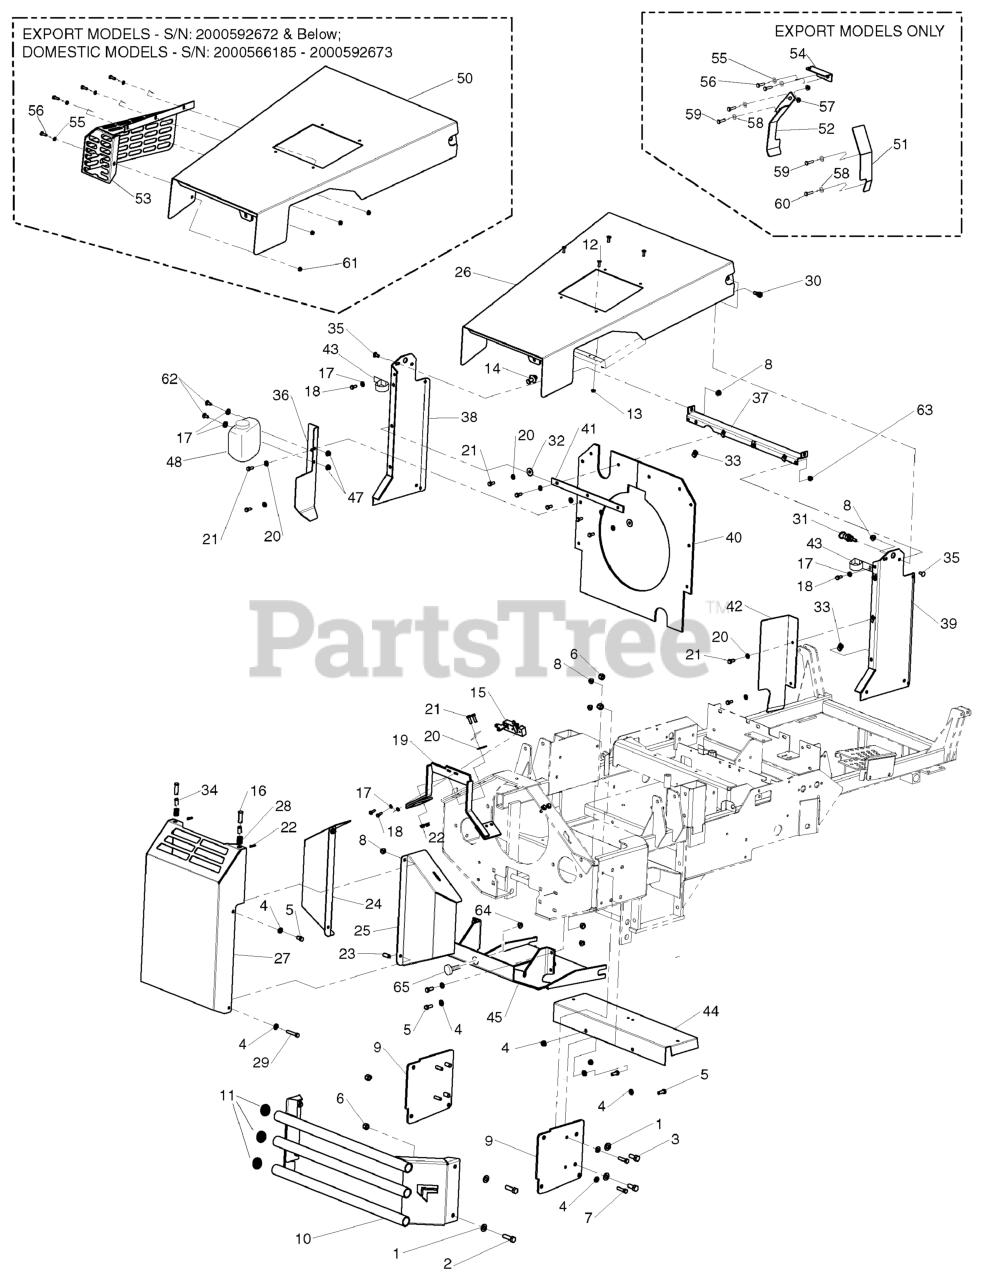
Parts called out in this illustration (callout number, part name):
1	WASHER, 1/2 SAE
2	BOLT, 1/2-20 X 1-3/4" GD8 CZ
3	BOLT, 1/2-20 X 1-1/4" GD5 CZ
4	WASHER, 3/8 SAE
5	BOLT, 3/8-16 X 1" GD5 CZ
6	NUT, Hex, Nylon Lock, 1/2-20
7	BOLT, 3/8-16 X 1-1/4" GD5 CZ
8	NUT, 3/8-16 HEX NYLOCK FLANGE
9	PLATE, BUMPER MOUNT - RED
10	WELD, BUMPER, SERVICE IS4500 - RED
11	PLUG, PANEL, 1.25 - BLACK
12	SCREW, 1/4-20 X 1/2" ALLEN BH
13	NUT, 1/4-20 NYLOCK FLANGE
14	BOLT/WASHER ASM HOOD LATCH
15	HOOD LATCH, IS5000
16	BUMPER, RUBBER, 5/16-18
17	WASHER, 1/4 SAE
18	BOLT, 1/4-20 X 1" GD5 CZ
19	WELD, MOUNT HOOD LATCH - RED
20	WASHER, 5/16" SAE
21	BOLT, 5/16-18 X 1" GD5 YZ
22	NUT, 5/16-18 HEX NYLOCK FLANGE
23	SPACER, .38 X .50 X 1.00
24	WELD, BUMPER SIDE LH IS5000 - RED
25	WELD, BUMPER SIDE RH IS5000 - RED
26	WELD, IS5000 HOOD - RED
27	WELD, CENTER BUMPER IS5000 - RED
28	SPRING, HOOD LATCH
29	BOLT, 3/8-16 X 1-3/4" GD5 CZ
30	BOLT, 3/8-16 X 3/8", 1/2" SHOULDER
31	PIN, LATCH, SPR LOADED-PULL ACT
32	WASHER, .34 X 1.25 X 10 GA
33	BODY CLIP, 5/16-18-7GA MATERIAL
34	SPACER, .38 X .50 X .75
35	BOLT, 5/16-18 X 3/4", CARRIAGE
36	GUARD, FAN, LH - RED
37	SHROUD, SUPPORT
38	WELD, SHROUD CHANNEL - LH - RED
39	WELD, SHROUD CHANNEL, RH - RED
40	SHROUD, RUBBER, IS5100Z
41	BAR, RUBBER SUPPORT SIDE
42	GUARD, FAN, RH - RED
43	CLAMP, 5/16 DOUBLE, WIRE & TUBE
44	SHIELD, DEBRIS - RED
45	WELD, SKID PLATE - RED
47	NUT, 1/4-20 HEX SERR. FLANGE
48	EXPANSION TANK
50	WELD, HOOD, IS5100ZCE - RED
51	GUARD, FLYWHEEL RH
52	GUARD, FLYWHEEL LH
53	WELD, MUFFLER GUARD
54	GUARD, HOOD LATCH
55	WASHER, 1/4 SAE
56	BOLT, 1/4-20 X 3/4"
57	NUT, 5/16-18 NYLOCK
58	WASHER, 5/16" SAE
59	BOLT, 5/16-18 X 1"
60	BOLT, 5/16-18 X 1-1/4"
61	NUT, 1/4-20 NYLOCK
62	BOLT, 1/4-20 X 3/4"
63	NUT, 1/4-20 HEX SERR. FLANGE
64	NUT, 5/16-18 LOCK
65	BUMPER, RUBBER, 5/16
